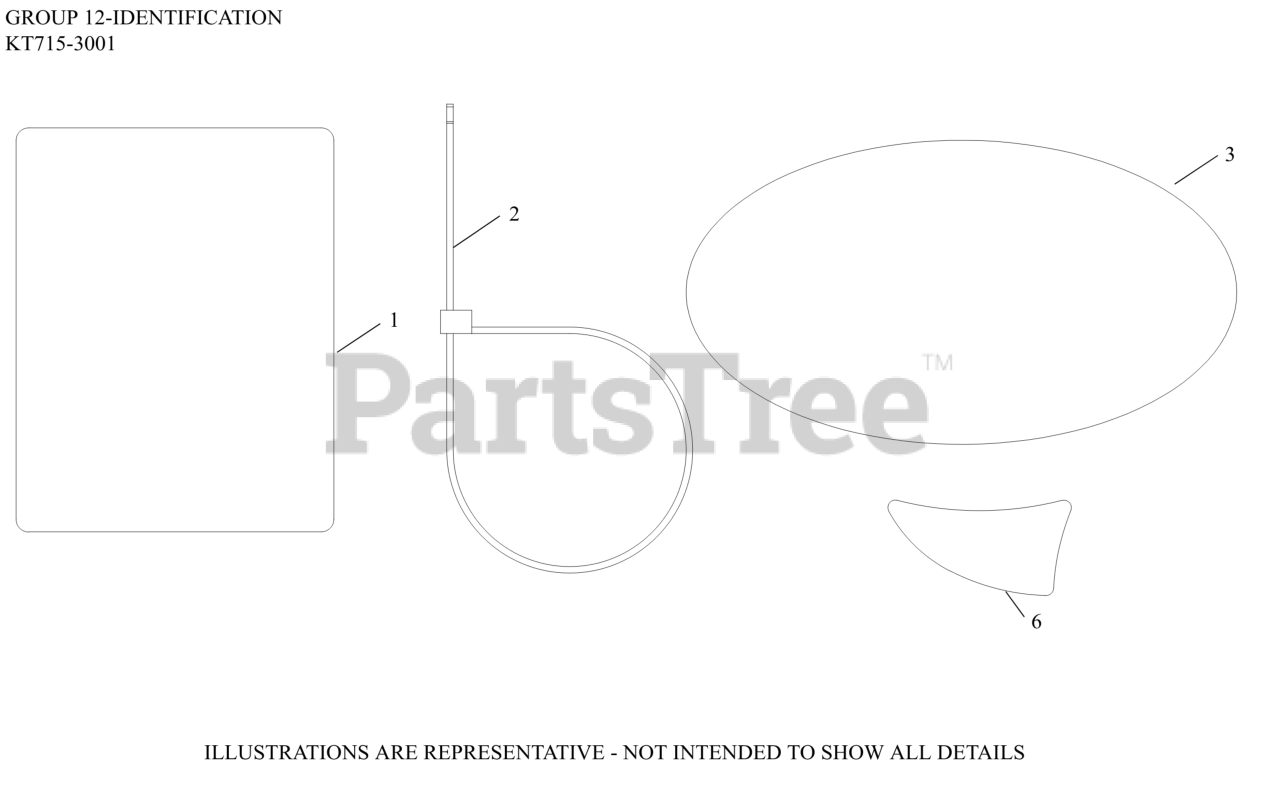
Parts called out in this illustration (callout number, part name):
1	LABEL, CLEAR LAMINATION
3	LABEL, 7000 SERIES (20HP, PRO)
6	LABEL, HI PERFORMANCE AIR FILTRATION
